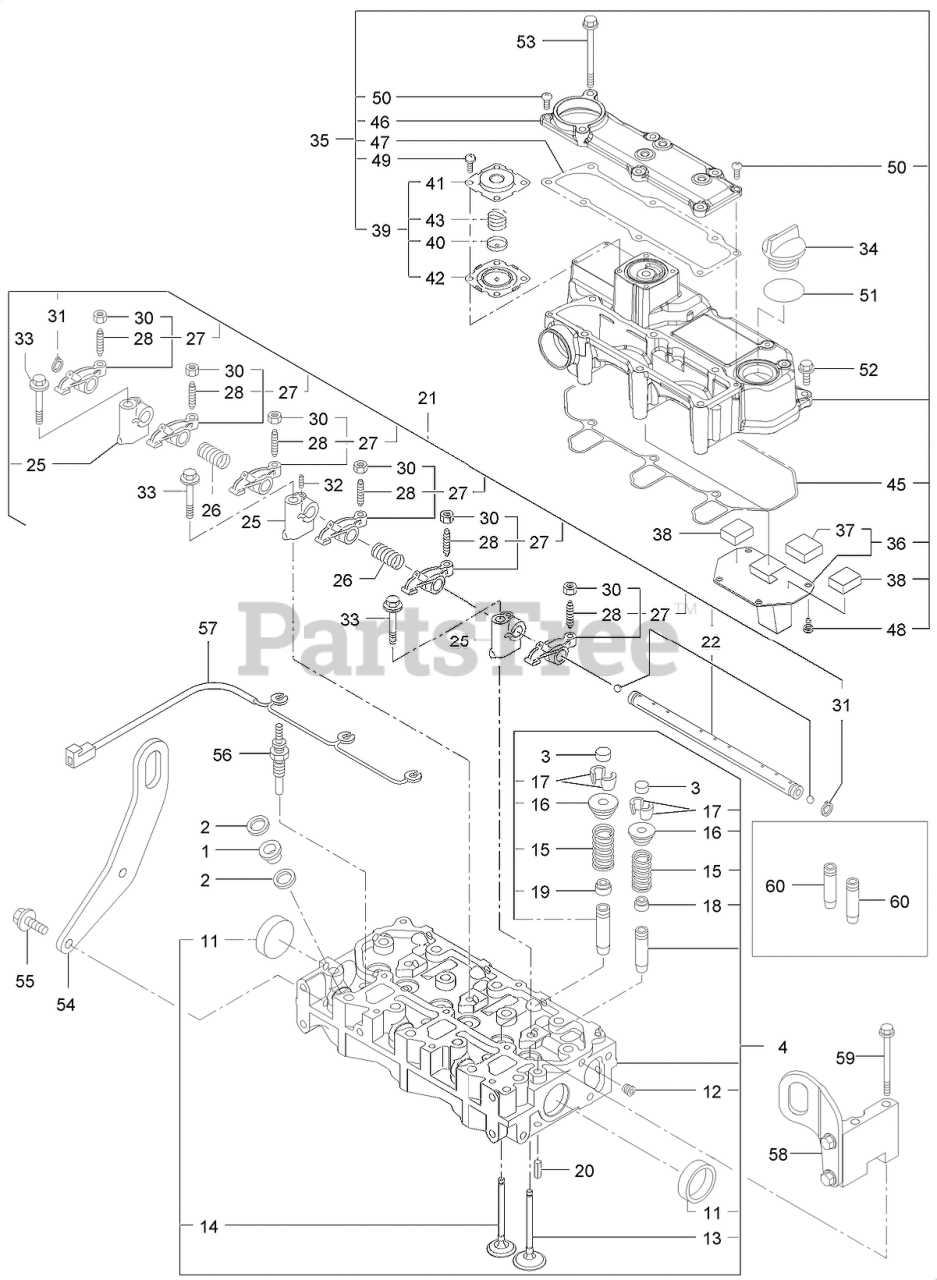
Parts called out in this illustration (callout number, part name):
1	PROTECTOR-NOZZLE
2	GASKET-NOZZLE
3	CAP-VALVE
4	Head ASM-Cylinder
11	PLUG-CUP
13	VALVE-SUCTION
14	VALVE, EXHAUST 3
15	SPRING-VALVE
16	RETAINER
18	SEAL-STEM, VALVE
19	SEAL-STEM, VALVE
20	PIN-SPRING
21	SUPPORT ASM-ROCKER
22	SHAFT ASM-ROCKER
25	SUPPORT-ROCKER ARM
26	SPRING-ROCKER
27	ARM ASM-ROCKER
28	SCREW-ADJUST, VALVE
34	COVER-FILLER
35	BONNET ASM
36	PLATE-BAFFLE
37	BAFFLE-BREATHER
38	BAFFLE-BREATHER
39	DIAPHRAGM ASM
40	PLATE-DIAPHRAGM
41	COVER-DIAPHRAGM
42	DIAPHRAGM
43	SPRING-DIAPHRAGM
45	GASKET-BONNET
46	COVER ASM-BONNET
54	LIFTER-ENGINE
56	PLUG-GLOW
57	CONNECTOR-GLOW PLUG
58	LIFTER ASM
